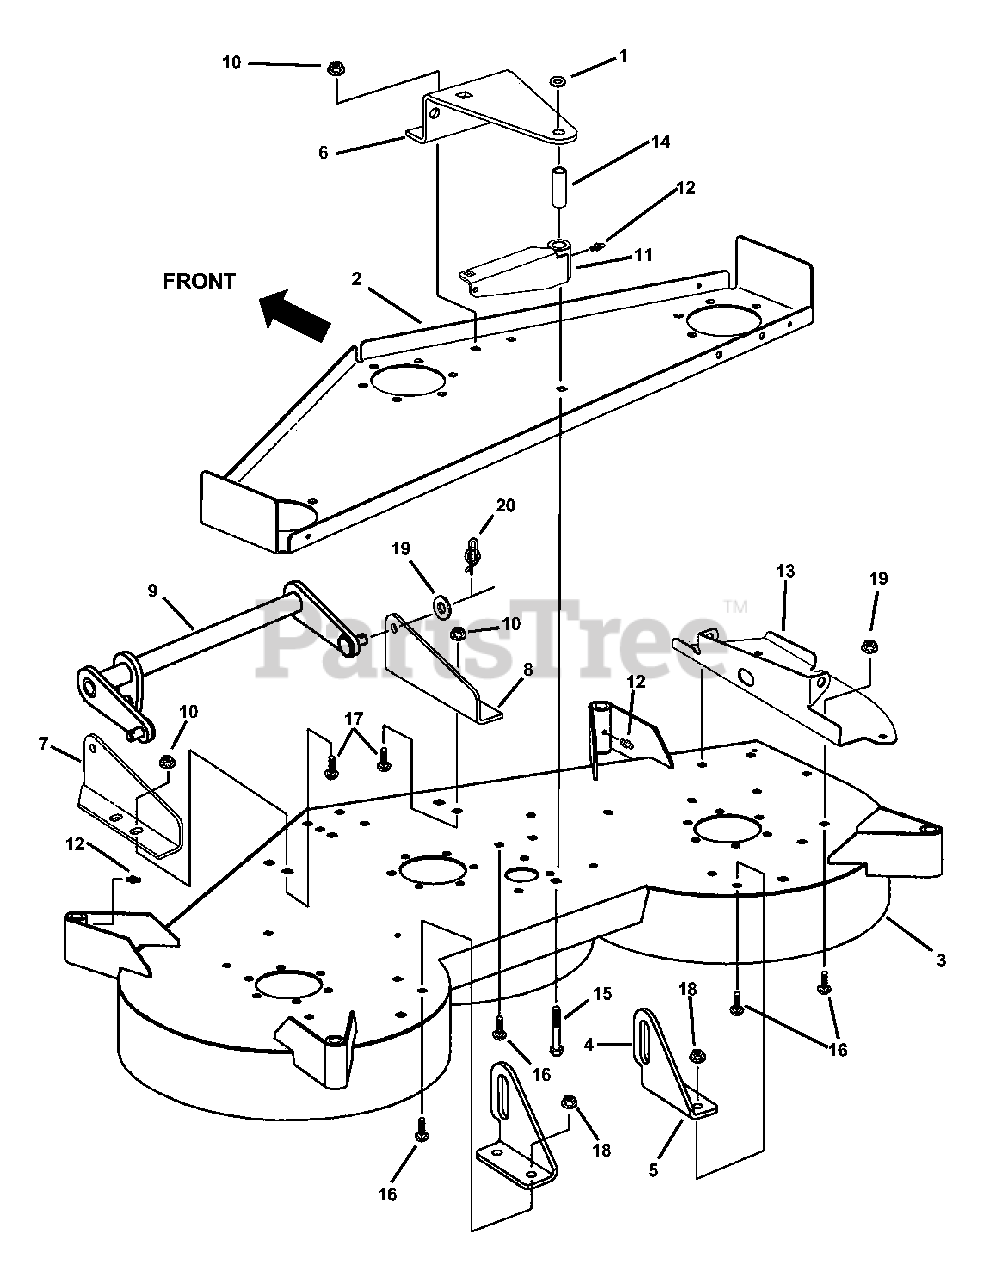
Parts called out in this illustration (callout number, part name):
1	RETAINER, 3/8" Bolt
2	STIFFENER, Deck
3	WELDMENT, 48" Deck
4	HANGER, R.H. Rear
5	HANGER, L.H. Rear
6	BRACKET, Pulley Mounting
7	BRACKET, L.H. Front Lift
8	BRACKET, R.H. Front Lift
9	WELDMENT, Front Lift Arm
10	NUT, 3/8-16 Hex Flange Lock
11	ASSEMBLY, Idler Arm/Lube Fitting
12	LUBE FITTING, Straight (press-fit for .187 dia. Hole)
13	BRACKET, Hinge (48" Deck)
14	SPACER, Pivot Collar
15	BOLT, 3/8-16 x 4" Square Neck Carriage, Grade 5
16	BOLT, 5/16-18 x 5/8" Short Neck Carriage, Grade 5
17	BOLT, 3/8-16 x 1" Short Neck Carriage, Grade 5
18	NUT, 5/16-18 Hex Flange Lock, Grade 5
19	WASHER, 3/8" Flat
20	PIN, 3/64 x 1-7/32" Locking Cotter
